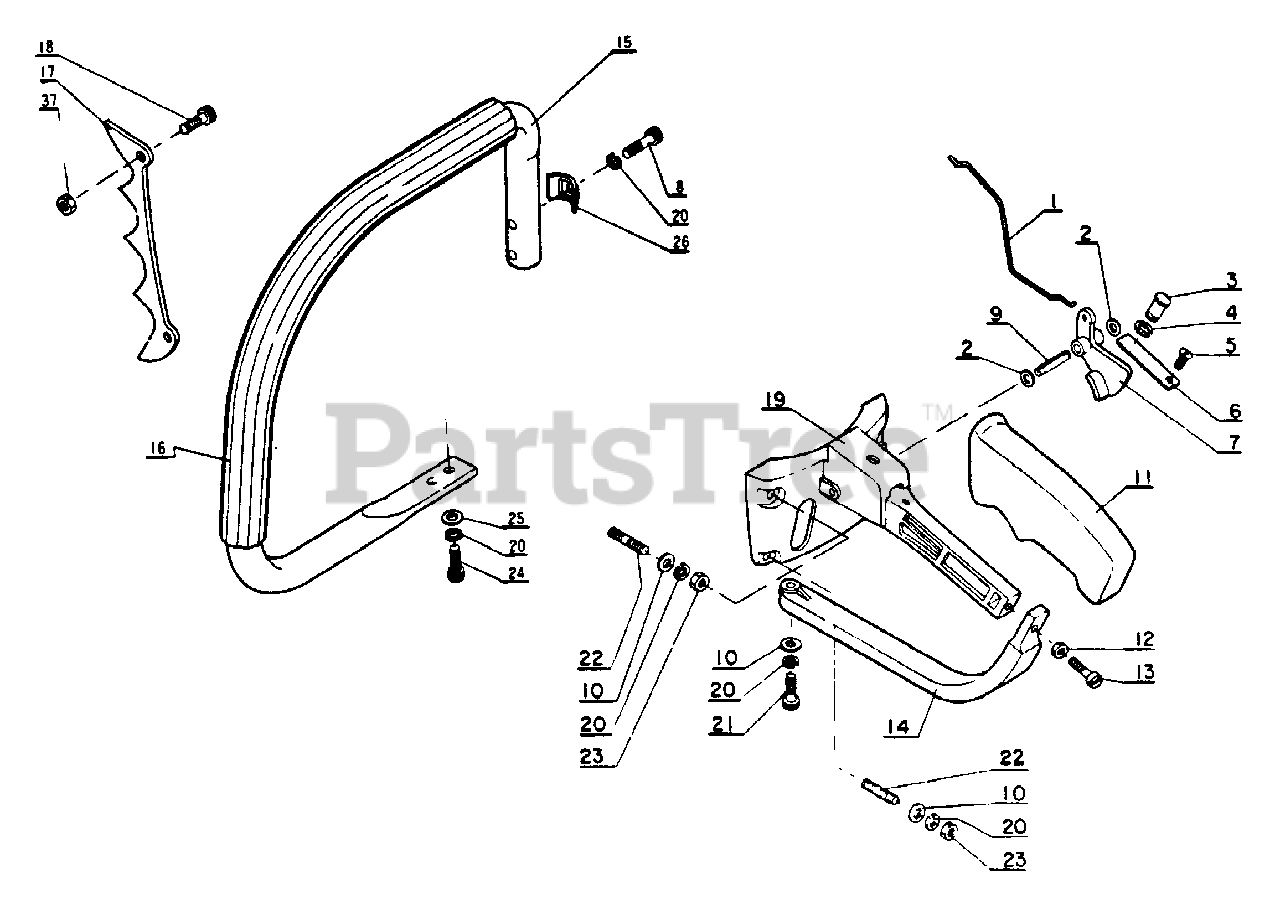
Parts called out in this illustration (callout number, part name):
1	ROD, CHOKE
2	WASHER - 5
3	LOCKOUT, THROTTLE
4	RING, RETAINING
5	SCREW
5	SCREW - 5X8
6	SPRING, TRIGGER
7	TRIGGER, THROTTLE
8	SCREW - 6X35
10	WASHER - 6
11	COVER, HANDLE
12	NUT
12	NUT - 5
13	SCREW - 5X25
13	BOLT - 5X25
14	SUPPORT, HANDLE
15	HANDLE - FRONT
16	GRIP, HANDLE
17	SPIKE
18	BOLT - 6X14
19	HANDLE - RIGHT
20	LOCKWASHER - 6
21	BOLT
23	LOCKNUT - 6
24	BOLT
25	WASHER
26	Handle set plate
37	NUT
